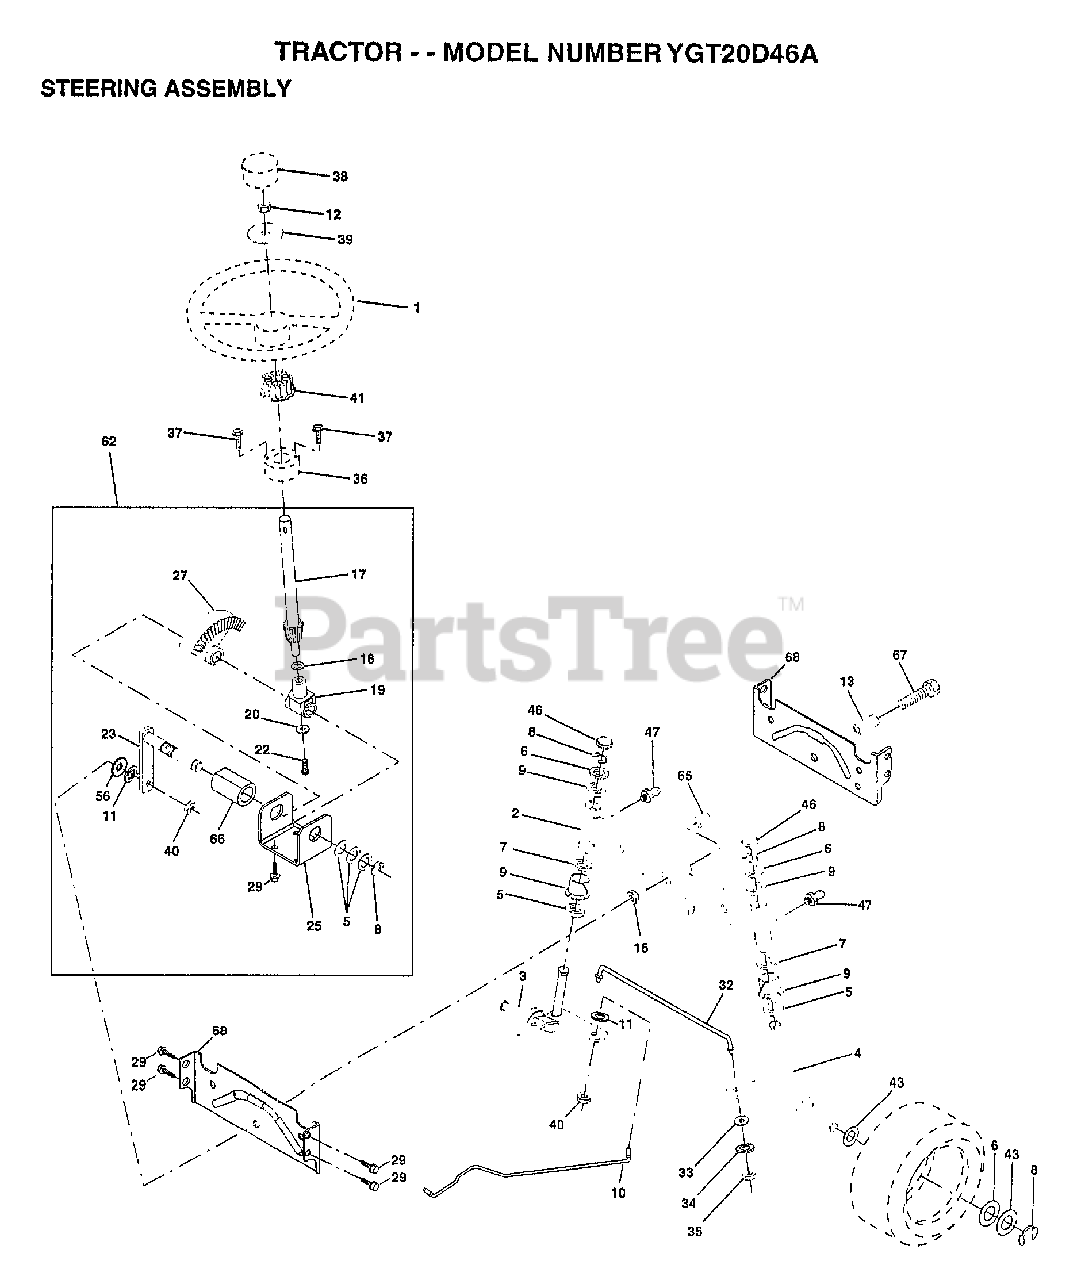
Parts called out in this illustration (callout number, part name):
1	WHEEL STR AYP BLK
2	AXLE ASM
3	"SPINDLE ASM,RH"
4	"SPINDLE AMS,LH"
5	WASHER .T
6	WASHER
7	WASHER
8	RING
9	COL. SRTG. BEAR.
10	DRAGLINK-STAMPED
11	LOCKWASHER
13	BEARING AXLE
15	"NUT-LOC,FLANGE LT"
17	STEERING SHAFT
18	THRUST WASHER
19	SUPPORT.SHAFT
22	SCREW HEX SOC1/4-
25	BRKT-STEERING
27	GEAR SECTOR
29	SCREW
32	ROD.TIE.19.75
33	WASHER M
34	LOCKWASHER
35	NUT.LOCK.5/16-24
36	BUSHING.STRG.3/4
37	"SCREW-TT,10-32 FL"
38	CAP STEER AYP
39	WASHER
40	GRIPCO NUT
41	ADAPTER LT
43	WASHER
46	CAP
47	ZERK M
56	WASHER
62	STEERING KIT
65	SPACER AXLE
66	"BEARING-ARM,PITMA"
67	BOLT
68	BRACE AXLE
